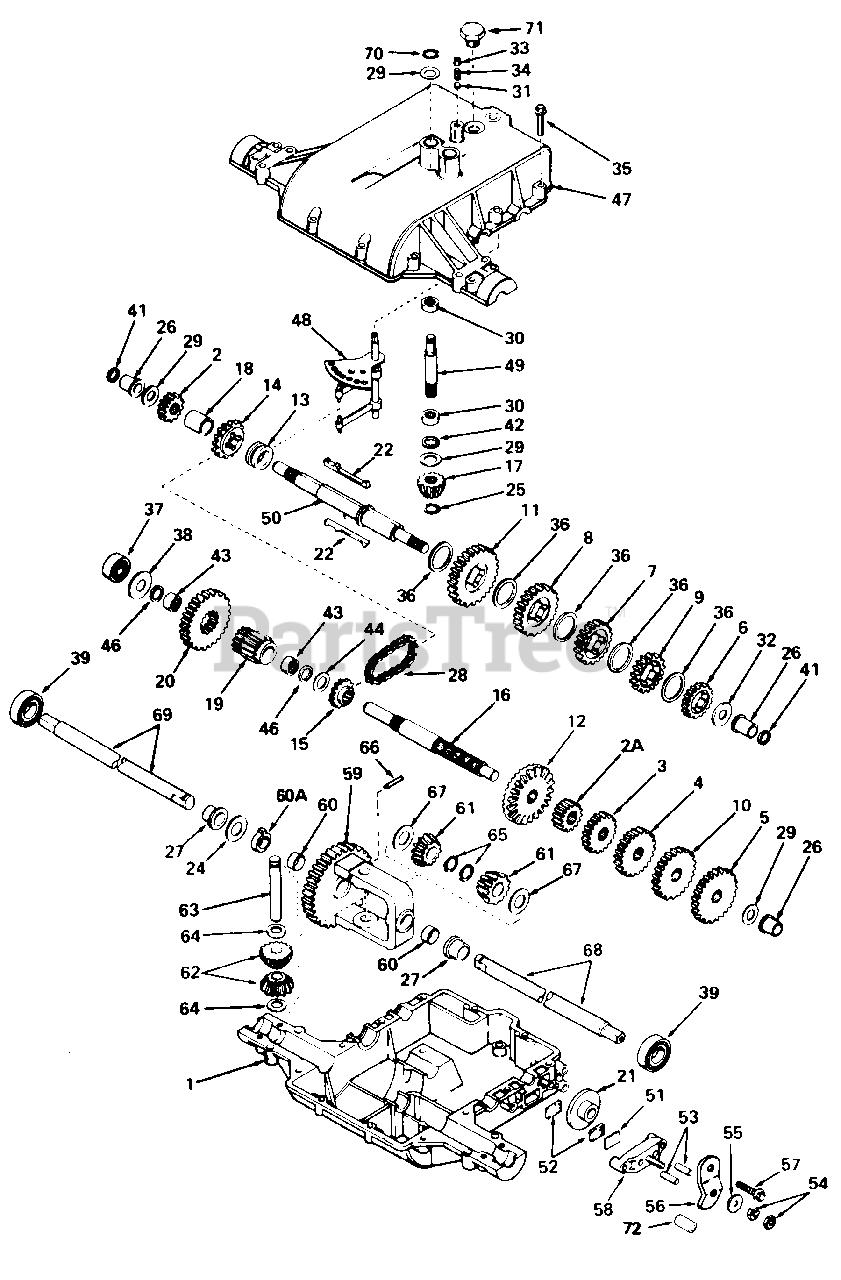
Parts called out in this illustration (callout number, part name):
1	Case, Transaxle
2	Gear, Spur (15 Teeth)
2A	Gear, Spur (12 Teeth)
3	Gear, Spur (20 Teeth)
4	Gear, Spur (25 Teeth)
5	Gear, Spur (30 Teeth)
6	Gear, Spur (20 Teeth)
7	Gear, Spur (25 Teeth)
8	Gear, Spur (30 Teeth)
9	Gear, Spur (22 Teeth)
10	Gear, Spur (28 Teeth)
11	Gear, Spur (37 Teeth)
12	Gear, Bevel (42 Teeth)
13	Collar, Shift
14	Sprocket (18 Teeth)
15	Sprocket (9 Teeth)
16	Shaft, Counter
17	Bevel Pinion, Input
18	Spacer
19	Pinion, Output
20	Gear, Output
21	Disc, Brake
22	Key
24	Washer
25	Ring, Retaining
26	Bushing, Flanged
27	Bushing, Flanged
28	Chain, Roller (No. 41 Chain, 22 Links)
29	Washer, Thrust
30	Bearing, Needle
31	Ball, Steel
32	Washer, Thrust
33	Screw, Set, 3/8-16 x 3/8
34	Spring
35	Screw, Hex Hd., Thread Forming, 1/4-20 x 1-1/4
36	Washer, Thrust
37	Bearing, Ball
38	Washer, Flat
39	Bearing, Ball
41	Ring, Square Cut
42	Ring, Square Cut
43	Bearing, Needle
44	Washer, Flat
46	Ring, Square Cut
47	Cover, Transaxle
48	Rod & Fork Assy., Shift
49	Shaft, Input
50	Shaft, Brake
51	Plate, Brake Pad
52	Pad, Brake
53	Pin, Dowel
54	Locknut, 5/16-24
55	Washer, Flat
56	Lever, Brake
57	Screw, Hex Hd., Thread Forming, 1/4-20 x 1-1/4
58	Holder, Brake Pad
59	Gear Assy., Differential
60	Bushing
60A	Bushing
61	Gear, Bevel
62	Pinion, Bevel
63	Pin, Drive
64	Washer, Thrust
65	Ring, Retaining
66	Pin, Roll
67	Washer, Thrust
68	Axle (15-1/4" Long)
69	Axle (13-3/8" Long)
70	Ring, Retaining
71	Plug, Hex Hd., 9/16-18 Thread
72	Spacer
